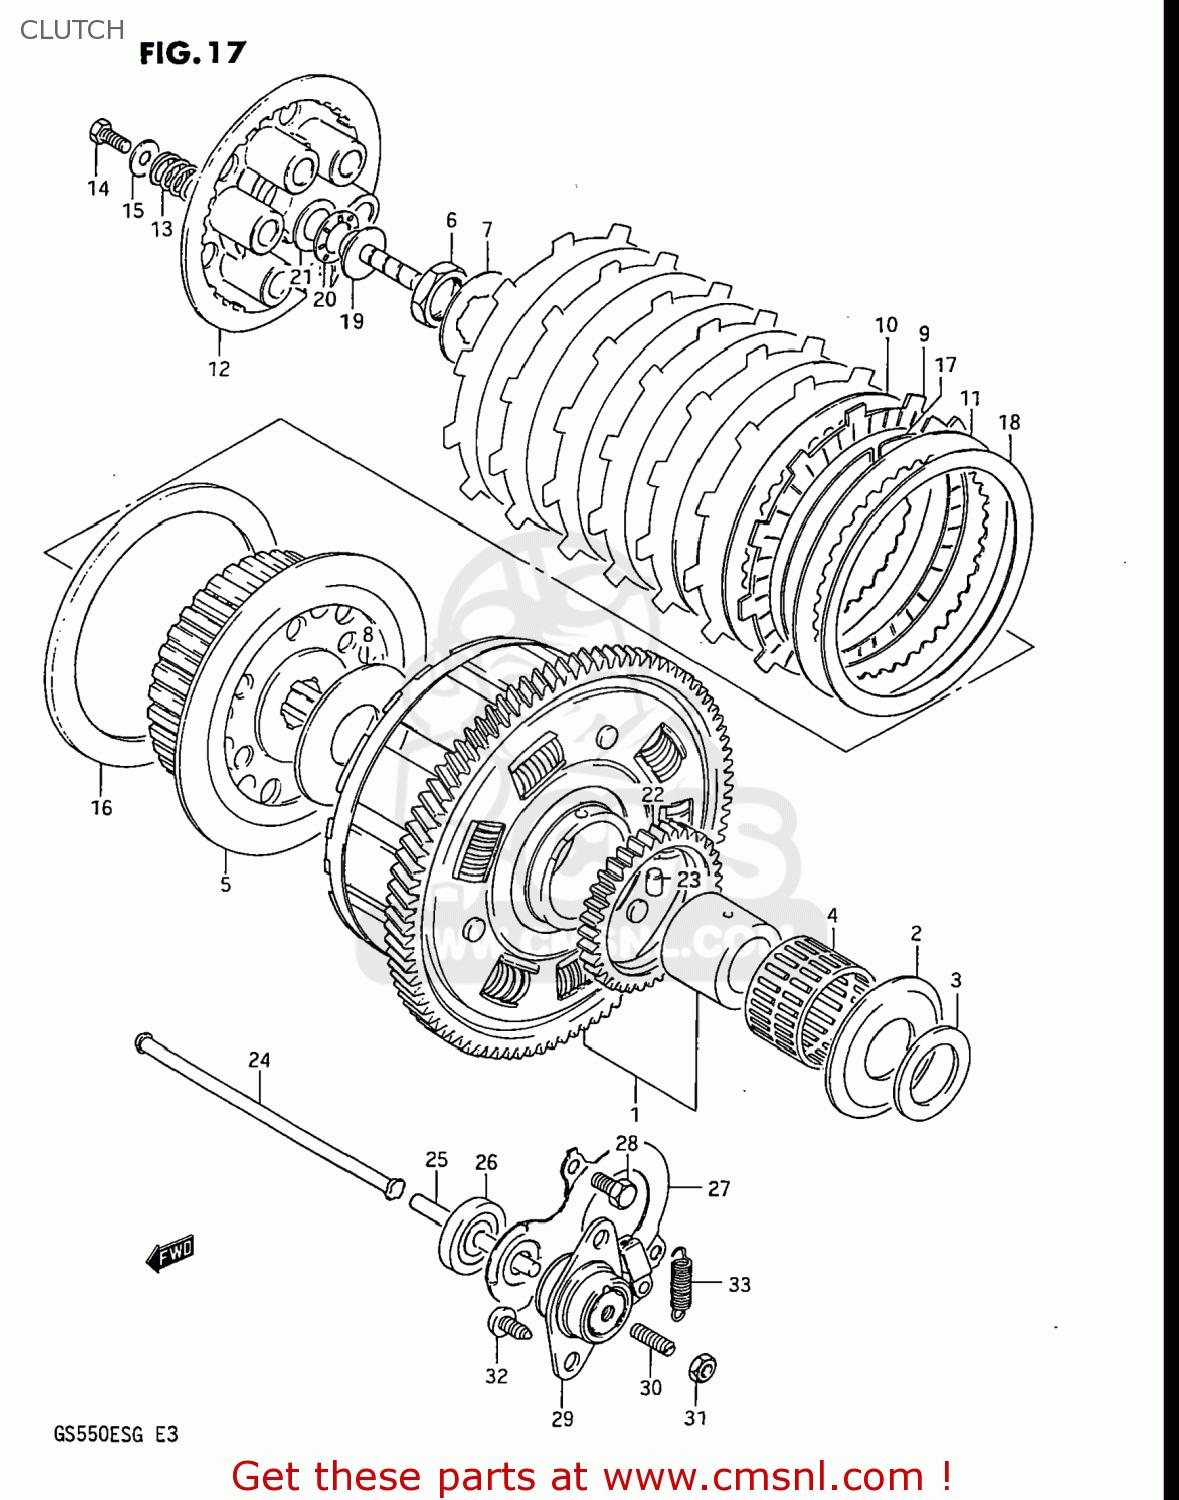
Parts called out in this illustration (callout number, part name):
1	GEAR ASSEMBLY,PRIMARY DRIVE
2	WASHER
3	WASHER
4	BEARING(40X45X32)
5	HUB,CLUTCH SLEEVE
6	NUT
7	WASHER,LOCK
8	WASHER
9	PLATE,CLUTCH DRIVE (NAS)
10	PLATE,CLUTCH DRIVEN (NAS)
11	PLATE,CLUTCH DRIVEN(T:2.0) (NAS)
12	DISC,CLUTCH PRESSURE
13	SPRING
14	BOLT, UPPER
15	WASHER
16	SEAT,WAVE WASHER
17	RING,STOPPER
18	WASHER
19	PIECE,CLUTCH PUSH
20	BEARING(15X28X2)
21	WASHER
22	GEAR,OIL PUMP DRIVE
23	PIN
24	ROD,CLUTCH PUSH
25	ROD,CLUTCH PUSH,L
26	SEAL,OIL(6X34X7.5)
27	PLATE,CLUTCH PUSH ROD
28	BOLT
29	SCREW ASSY,CLUTCH RELEASE
30	SCREW(6X25)
31	NUT 6MM
32	SCREW
33	SPRING
